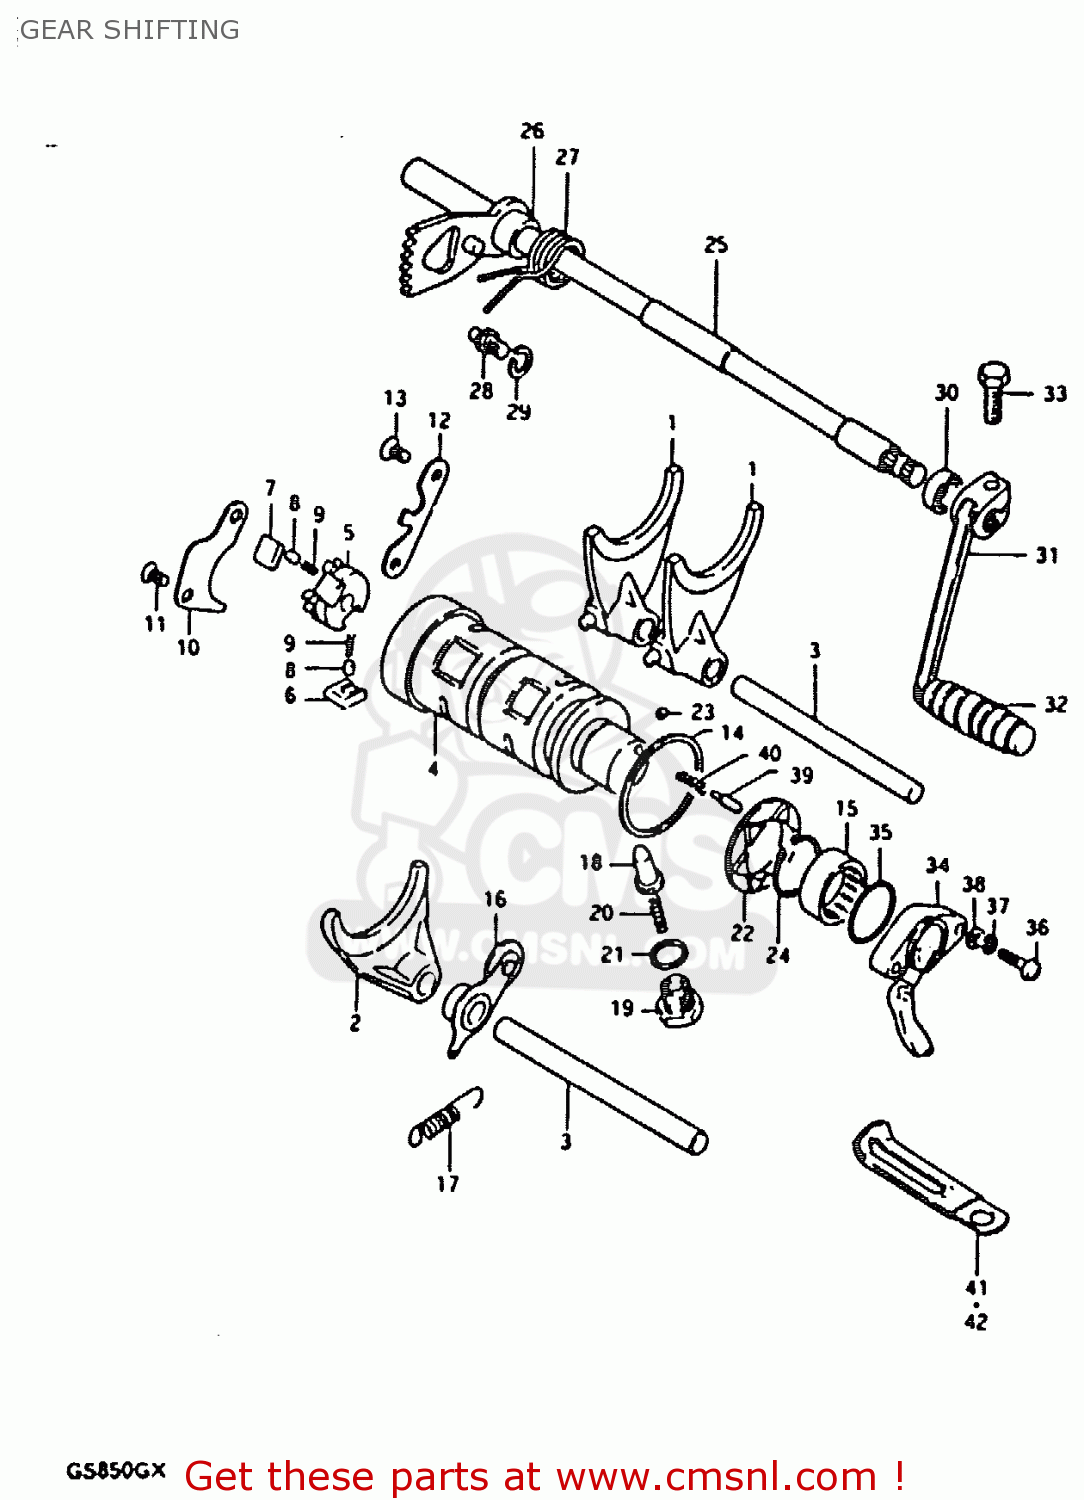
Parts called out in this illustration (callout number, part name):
1	FORK,GEAR SHIFT NO.1
2	FORK,GEAR SHIFT NO.3
3	SHAFT,GEAR SHIFT FORK
4	CAM,GEAR SHIFT
5	RETAINER,GEAR SHIFT CAM
6	PAWL,GEAR SHIFT NO.1
7	PAWL,GEAR SHIFT NO.2
8	PIN(5X8)
9	SPRING
10	LIFTER,GEAR SHIFT PAWL
11	SCREW
12	GUIDE,GEAR SHIFT CAM
13	SCREW
14	WASHER(40X45X1)
15	BEARING(25X32X12)
16	STOPPER,GEAR SHIFTING
17	SPRING
18	STOPPER,GEAR SHIFT CAM NO.2
19	HOLDER,GEAR SHIFT CAM STOP SPR
20	SPRING
21	GASKET(14X19.2X2) (NAS)
22	PLATE,GEAR SHIFT CAM STOPPER
23	PIN 4X6
24	CIRCLIP
25	SHAFT,GEAR SHIFT
26	SPACER (12X20X12)
27	SPRING
28	STOPPER,GEAR SHIFT CAM
29	WASHER
30	OIL SEAL
31	LEVER ASSEMBLY,GEAR SHIFTING
32	RUBBER,GEAR SHIFT PEDAL
33	BOLT
34	TERMINAL BASE ASSY,GEAR SHIFT
35	O-RING (D:2.4 ID:26.2)
36	SCREW 5X20
37	LOCK WASHER
38	WASHER
39	PIN(5X15.5)
40	SPRING
41	CLAMP L:35
42	CLAMP
